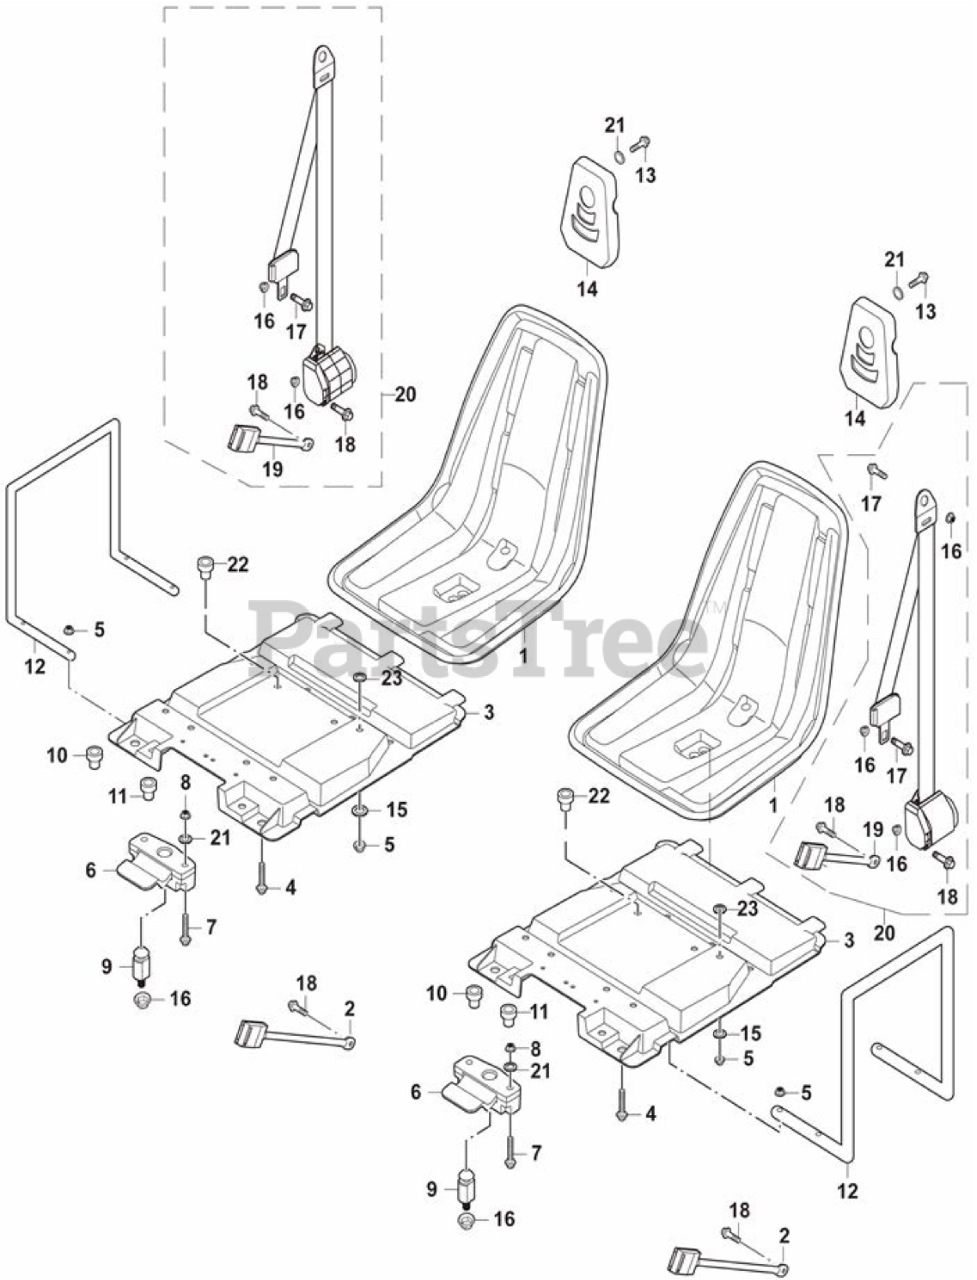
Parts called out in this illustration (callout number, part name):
1	Seat Assy I
2	Safety belt lock latch I
3	Seating Mounting Plate I
4	Hexagon Flange BoltM8X30
5	Hexagon Flange Bolt M8
6	Front Seat Cushion Lock Hook
7	Hexagon Flange Bolt M6X40
8	Hexagon Flange Nut M6
9	Lock Bracket, Seat
10	Pluged Damping Pad 12X4
11	Pluged Damping Pad 10X14
13	Hexagon Flange Bolt M6X25
15	Flat Washer 8X28X1.5
16	Flat Washer10X25X3
17	Hexagon Step Bolt M10X14X5X22
18	Hexagon Flange bolt M10X1.25X20
19	Seat Belt Locker I
20	Safety belt
21	Flat washer 6
22	Turnup Liner 8.4X25X8
23	Flat Washer10X25X3
